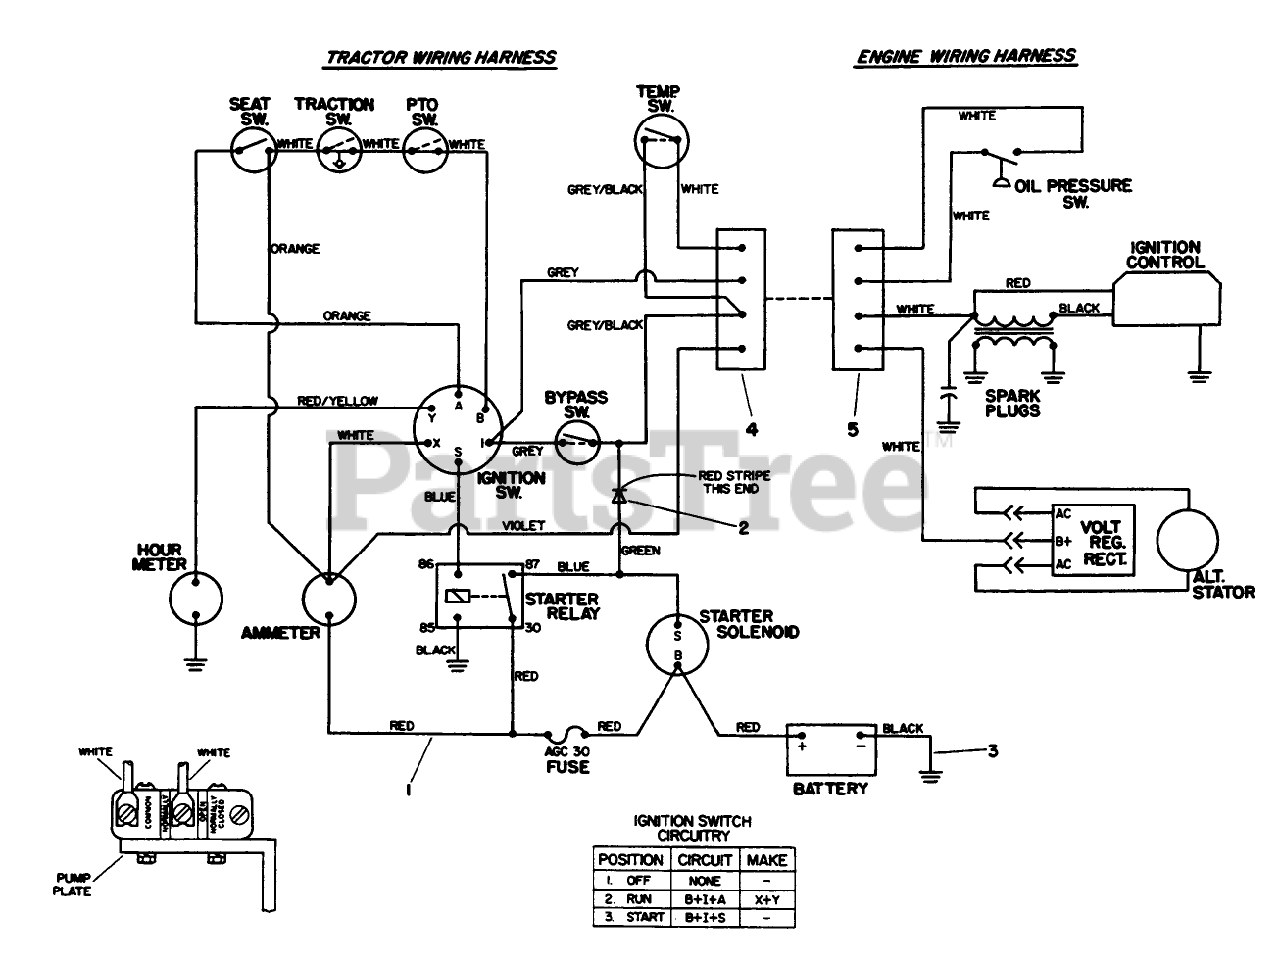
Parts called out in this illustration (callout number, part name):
1	Harness-Wire (Incl. Ref. #2)
2	DIODE ASM
3	BATTERY GROUND WIRE
4	TAB HOUSING
5	RECEPTACLE HOUSING
